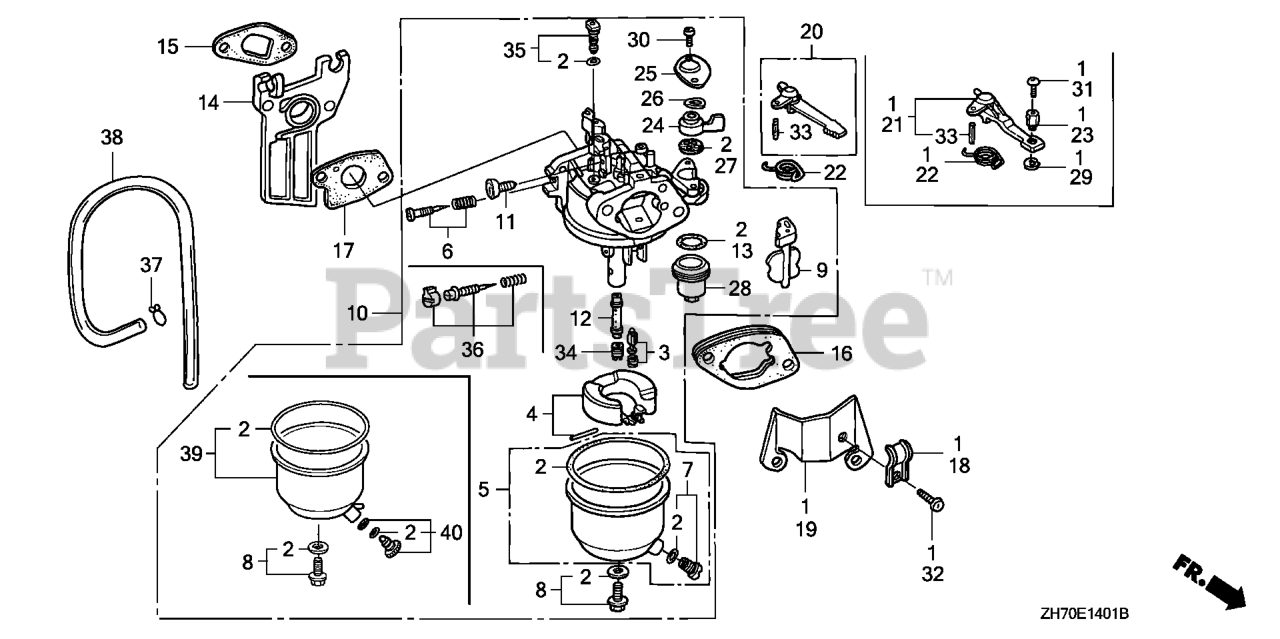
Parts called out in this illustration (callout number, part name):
2	GASKET SET
3	VALVE SET, FLOAT (CARBURETOR NO.) (SEAT NOT INCLUDED)
4	FLOAT SET
5	CHAMBER SET, FLOAT (CARBURETOR NO.)
5	CHAMBER SET, FLOAT (CARBURETOR NO.) (FOR BE12A A)
6	SCREW SET, PILOT (Honda Code 1441500). (CARBURETOR NO.)
7	SCREW SET, DRAIN (Honda Code 1672187). (CARBURETOR NO.)
8	SCREW SET B
8	SCREW SET
9	CHOKE SET
10	CARBURETOR ASSY. (BE60B B)
10	CARBURETOR ASSY. (BE12A C)
11	SCREW, THROTTLE STOP
12	NOZZLE, MAIN (CARBURETOR NO.)
12	NOZZLE, MAIN
13	GASKET, FUEL STRAINER CUP
14	INSULATOR, CARBURETOR
15	GASKET, INSULATOR
16	SPACER, CARBURETOR
17	GASKET, CARBURETOR
20	LEVER, CHOKE (STD)
24	LEVER, VALVE
25	PLATE, LEVER SETTING (CARBURETOR NO.)
26	SPRING, PETCOCK LEVER (CARBURETOR NO.)
27	GASKET, VALVE
28	CUP, FUEL STRAINER
30	SCREW, PAN (3X6)
30	SCREW, PAN (3X8) (CARBURETOR NO.)
33	PIN, SPRING (2X12)
34	JET, MAIN (#55) (CARBURETOR NO.) Use up to Engine SN BE03A J.
34	JET, MAIN (#58) Use from Engine SN BE30B E.
34	JET, MAIN (#60)
35	JET SET, PILOT (#35)
36	SCREW SET (Honda Code 4219879). (CARBURETOR NO.)
